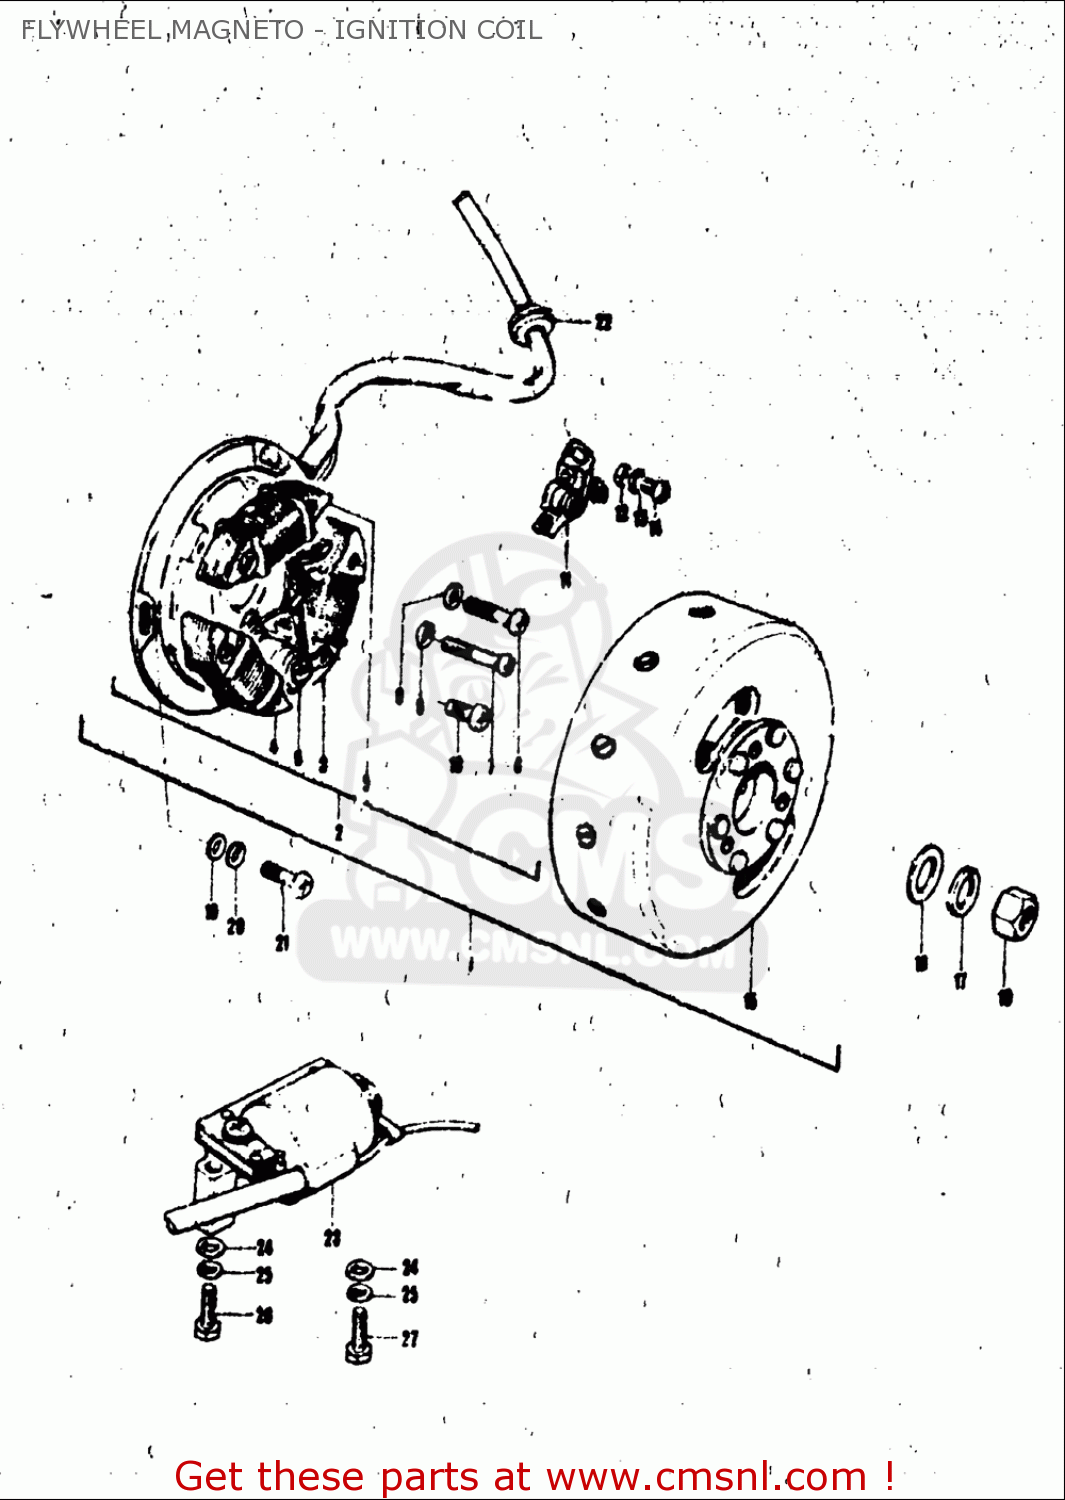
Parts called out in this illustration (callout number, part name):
8	WASHER,LOCK
9	CONDENSER
10	SCREW
11	POINT ASSY,CONTACT
12	WASHER
13	WASHER,LOCK
14	.SCREW
16	WASHER
17	WASHER,LOCK
18	NUT
19	WASHER
20	WASHER,LOCK
21	SCREW
23	COIL ASSY,IGNITION
24	WASHER
25	WASHER,LOCK
26	BOLT
